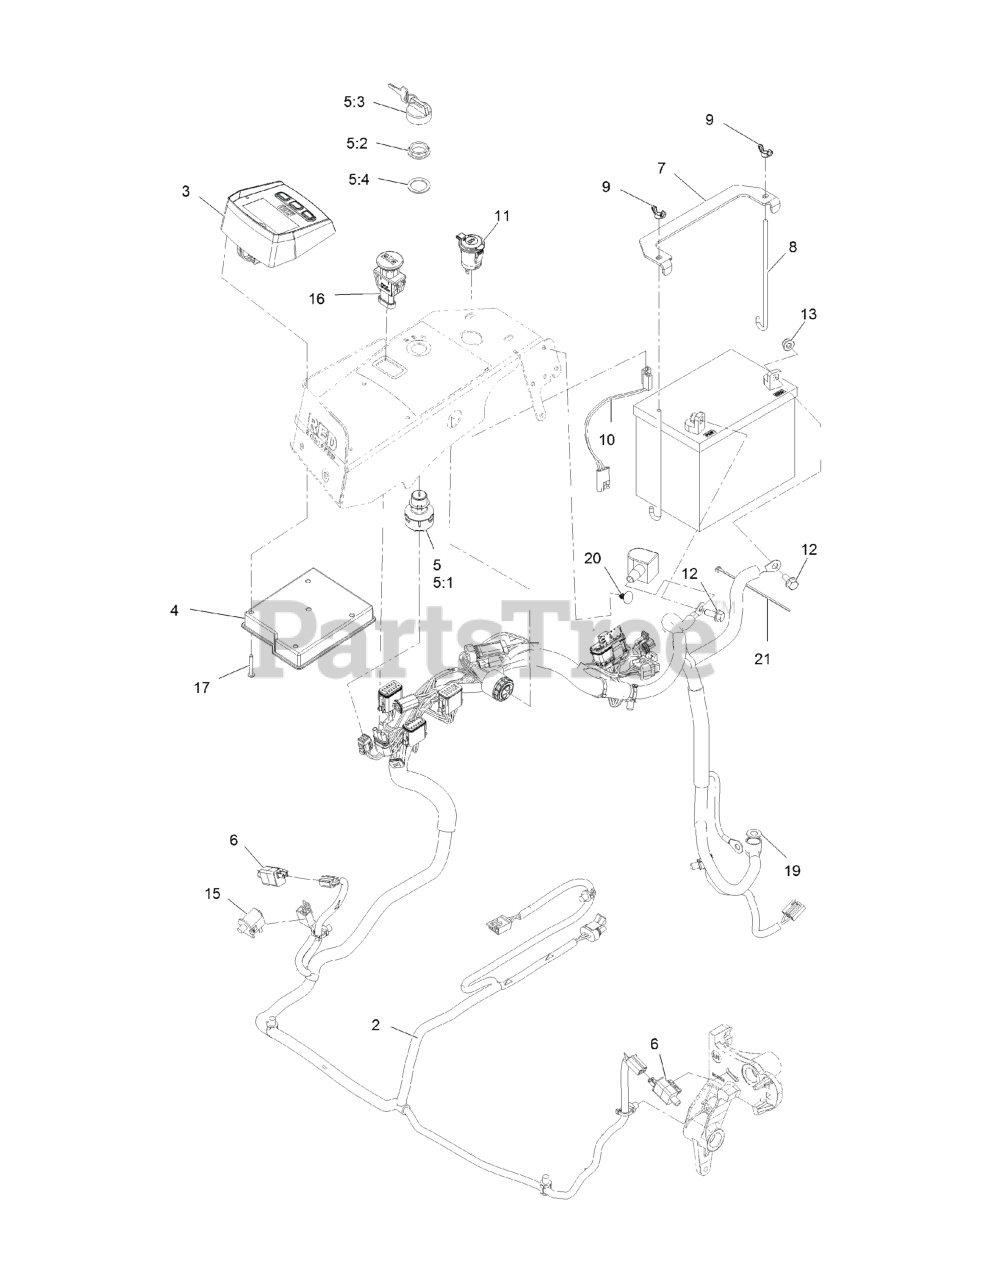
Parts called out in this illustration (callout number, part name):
2	HARNESS-WIRE
3	MODULE, LDU
4	Module-Mcu
5	IGNITION SWITCH ASM
5:1	Switch-Ignition
5:2	NUT-MOUNTING
5:3	IGNITION KEY SET
5:4	WASHER-BACKUP
7	STRAP-TIE DOWN, BATTERY
8	BOLT-HOLDDOWN
9	WINGNUT
10	HARNESS-RECEPTACLE, 12V
11	PORT-POWER, 12V
12	SCREW-HHF
13	NUT-HF, NI
15	SWITCH-BAIL
16	SWITCH-PTO, SEALED
17	SCREW-PPH
19	WASHER-FLAT
20	PLUG-PLASTIC
21	TIE-CABLE
